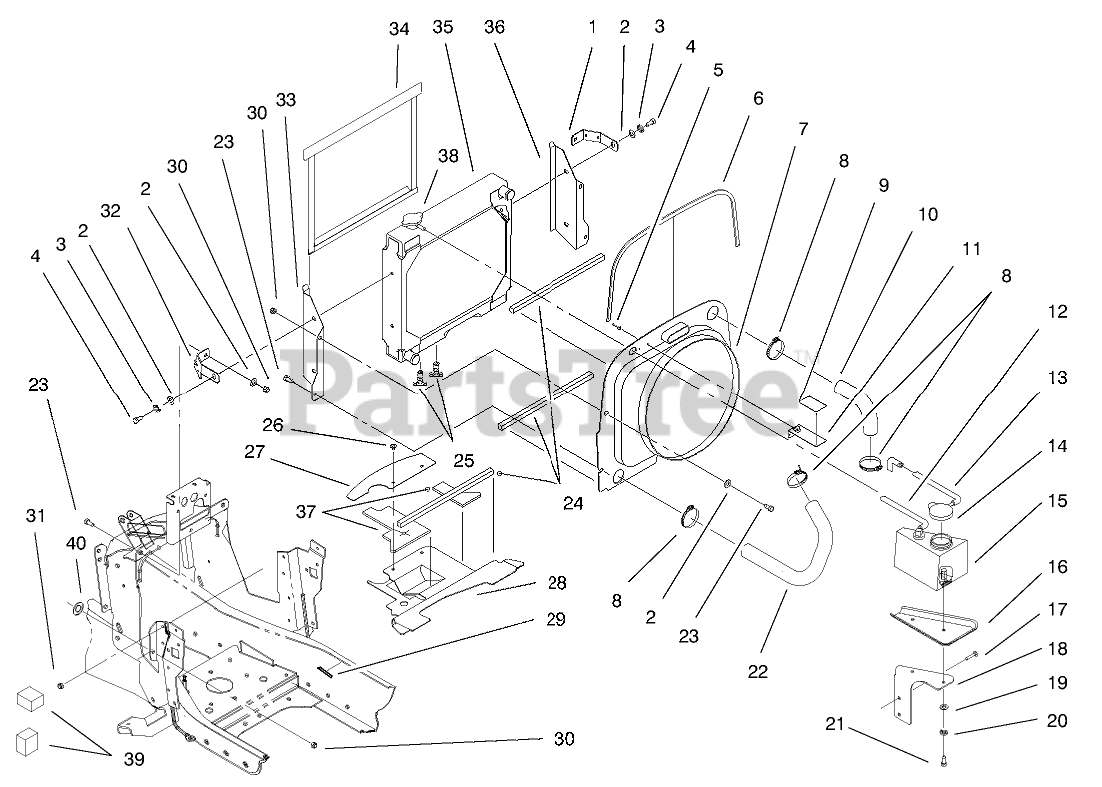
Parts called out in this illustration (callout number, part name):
1	Strap-Radiator
2	WASHER-PLAIN
3	WASHER-LOCK
4	SCREW-HH
5	RIVET-POP
6	TRIM - LOC 31"
6	Trim-Loc
7	SHROUD - FAN
8	CLAMP-HOSE
9	DECAL - WARNING
10	HOSE - RAD. DAIHATSU
11	FAN/DECAL ASM
12	HOSE - FUEL LINE
13	HOSE - OVERFLOW
14	CAP - COOLANT RESERVOIR
15	BOTTLE - OVERFLOW
16	TRAY - OVERFLOW
17	BOLT-CARR
18	Brkt-Bottle
19	WASHER-FLAT
20	WASHER-LOCK
21	SCREW-HH
22	HOSE - RAD. DAIHATSU
23	SCREW-HH
24	FOAM - RADIATOR/SHROUD
25	VALVE - DRAIN
26	RIVET - PLASTIC
27	BAFFLE - TOWER REAR
28	BAFFLE - TOWER
30	NUT-LOCK, NI
31	NUT-HEX
32	Bracket-Relay
33	Support-Radiator RH
34	SCREEN - CHAFF
35	RADIATOR - DIESEL
36	Support-LH Radiator
37	FOAM - BAFFLE
38	CAP-RADIATOR
39	SEAL-FOAM, SIDE
40	WASHER-WHEEL
